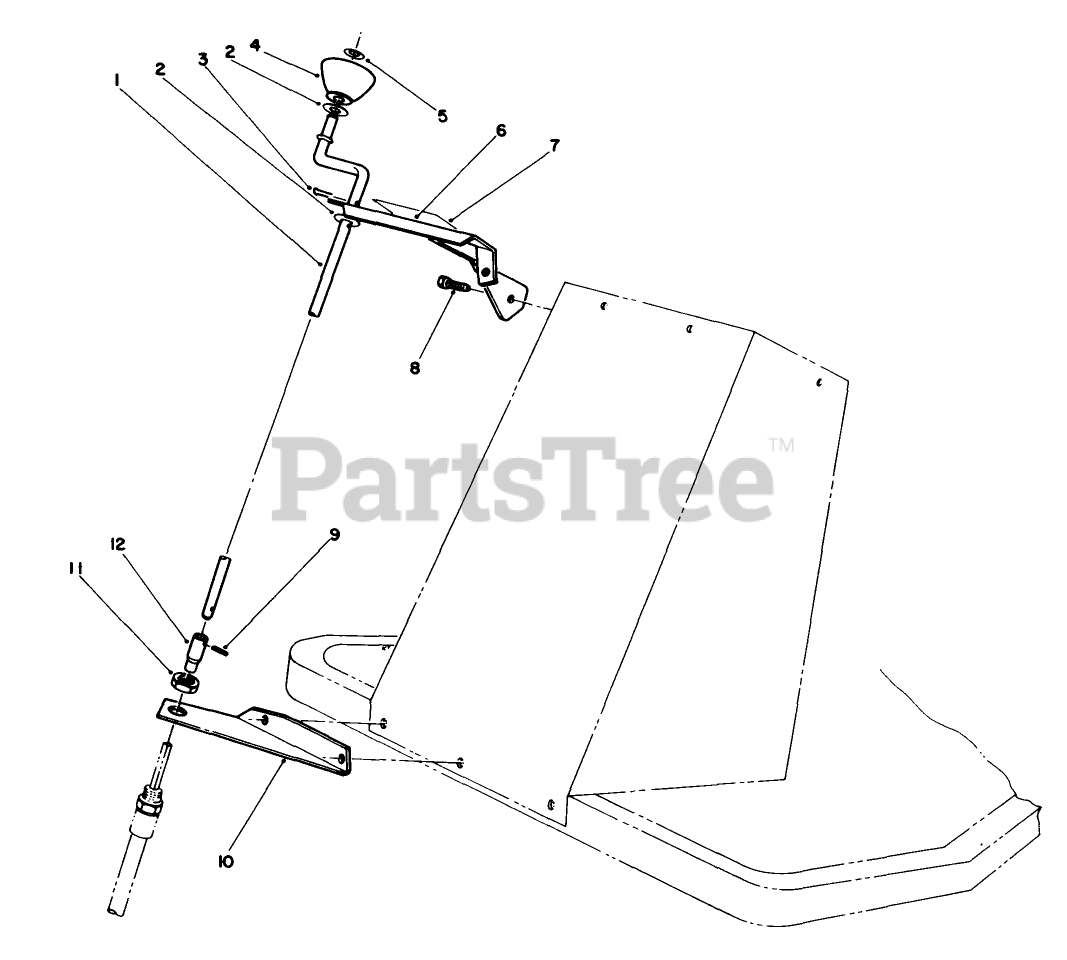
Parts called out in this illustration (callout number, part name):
1	CHUTE CONTROL ROD
2	WASHER-FLAT
3	PIN-COTTER
4	KNOB-CHUTE
5	NUT-PUSH
6	TOP BRKT R
7	Decal-Chute Rotation
8	SCREW-HH
9	PIN-SPRING
10	BOTTOM BRKT R
11	LOCKNUT
12	COUPLER
